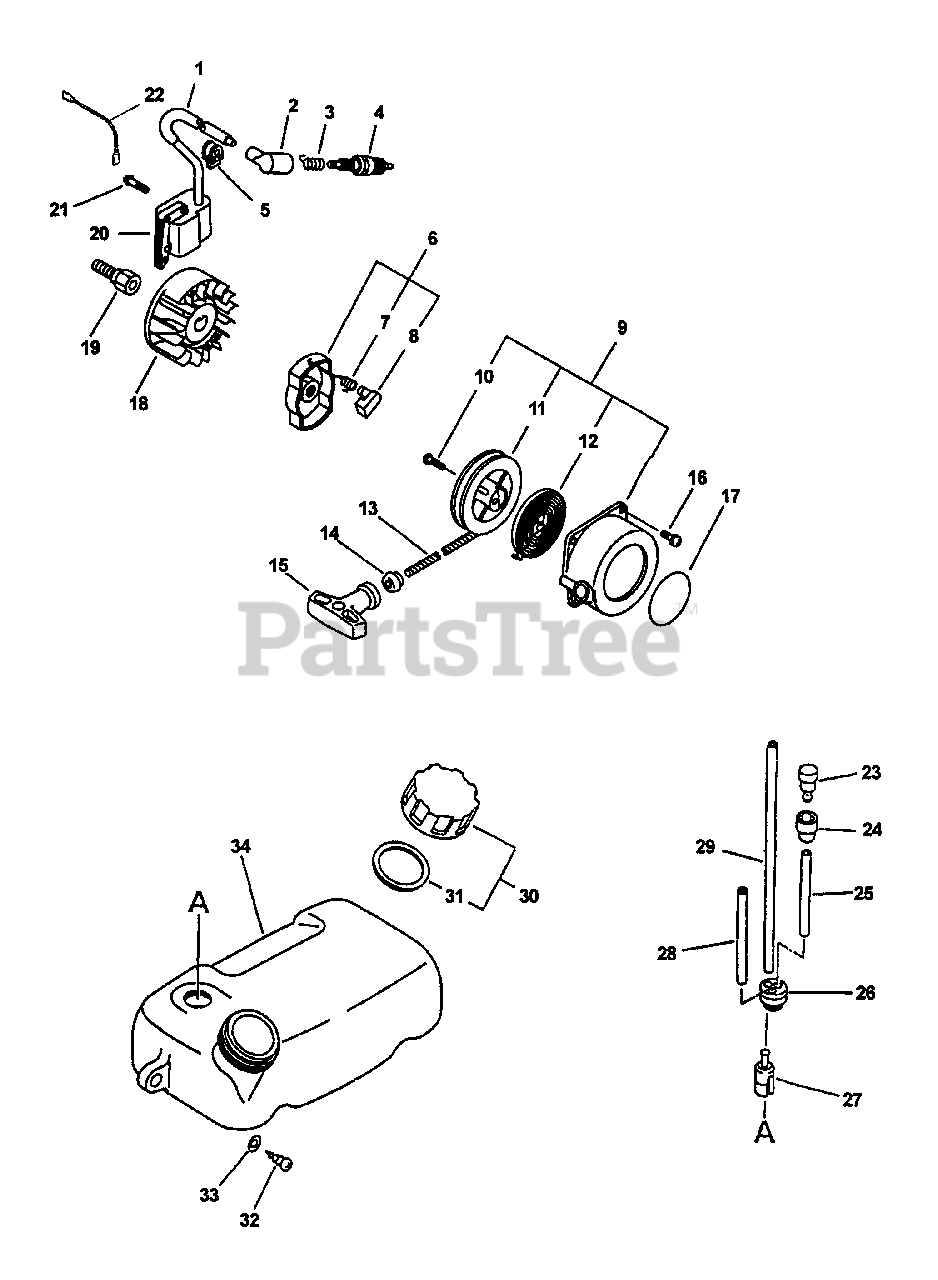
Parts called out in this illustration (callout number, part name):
2	CAP, SPARK PLUG
3	TERMINAL, SPARK PLUG CAP
4	SPARK PLUG -- BPM-7Y
6	STARTER PAWL ASSY
7	SPRING, RETURN
8	PAWL, STARTER - BLACK
9	STARTER ASSY
11	REEL, ROPE
12	SPRING, REWIND
13	ROPE, STARTER - 3.5X850
14	GUIDE, ROPE
15	GRIP, STARTER
16	SCREW - 4X16
17	LABEL - ECHO
18	FLYWHEEL
19	HUB, FAN
20	COIL, IGNITION
21	SCREW - 4X22
22	LEAD - GROUND
23	VENT, FUEL TANK
24	COVER, VENT
25	PIPE - 3X5X90 -- BLACK
26	GROMMET
27	FILTER, FUEL
28	PIPE - 3X6X110 -- CLEAR
29	PIPE - 3X5X210 -- BLACK
30	CAP ASSY
31	GASKET, CAP
32	SCREW - 5X20 -- TAPPING
33	WASHER - 5
34	TANK, FUEL
